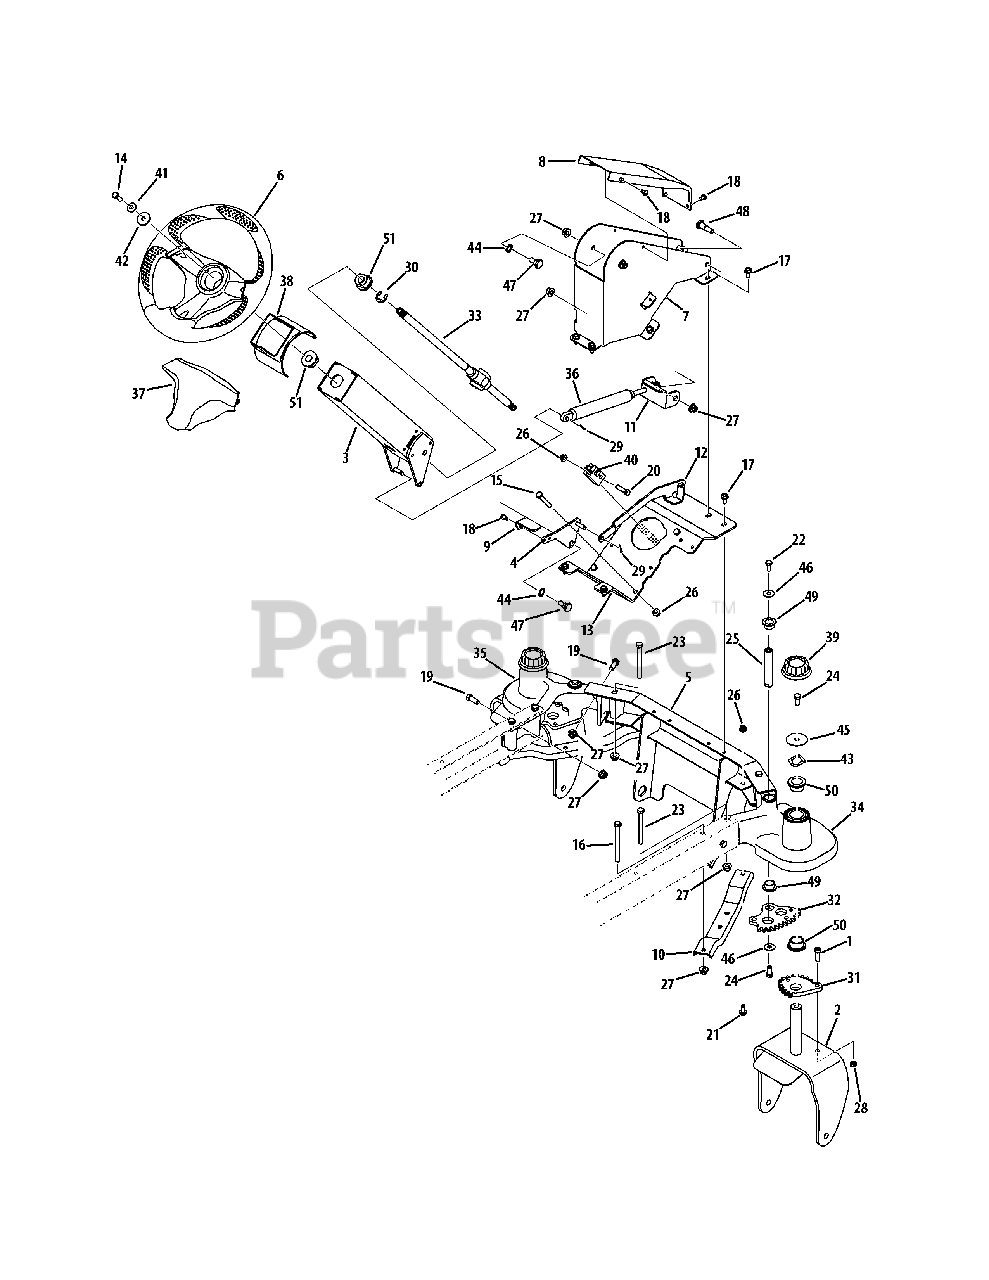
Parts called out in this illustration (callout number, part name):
1	Socket Head Screw, 5/16-18 x 1.00
2	Caster Bracket Assembly
3	Upper Steering Column Assembly
4	Tilt Release Pedal Assembly
5	Front Bumper Frame Assembly
6	Steering Wheel Assembly
7	Lower Steering Wheel Column
8	Lower Column Cover
9	Tilt Steering Pedal
10	Front Frame Brace
11	Damper Pivot Lower Bracket
12	Tilt Action Lever
13	Steering Mount Box Plate
14	Hex Screw, 5/16-18 x 1.00
15	Hex Screw, 5/16-18 x 2.25
16	Hex Screw, 3/8-16 x 4.00
17	Hex Washer Screw, 5/16-18 x .750
18	Screw, 1/4-20 x .5
19	Hex Screw, 3/8-16 x 1.00
20	Hex Screw, 5/16-18 x 1.25
21	Hex Washer Screw, 5/16-18 x 750
22	Hex Screw, 5/16-18 x .75
23	Hex Screw, 3/8-16 x 3.50
24	Hex Screw, 3/8-16 x .750
25	Pivot Gear Steering Shaft
26	Flange Lock Nut, 5/16-18
27	Flange Lock Nut, 3/8-16
28	Hex Lock Nut, 5/16-18
29	Cotter Pin, 3/32 x .750
30	E-Ring, .750
31	13-Tooth Variable Spur Gear
32	12-Tooth Variable Gear
33	Steering Shaft
34	RH Flange Bearing Caster Pivot
35	LH Flange Bearing Caster Pivot Axle
36	Locking Damper Cylinder, 80MM
37	Steering Wheel Cover
38	Column Cover
40	Steering Shaft Block
41	Bell Washer, .340 x .872 x .060
42	Flat Washer, .330 x 1.25 x .120
43	Wave Washer, 1.5 x 1.0 x .029
44	Wave Washer, .510 x.750 x .017
45	Flat Washer, .406 x 1.92 x .060
46	Flat Washer, .344 x 1.00 x .063
47	Shoulder Bolt, 3/8-16 x .496 x .336
48	Shoulder Screw, 3/8-16 x .50 x .66
49	Flange Bearing, 3/4 x .52
50	Flange Bearing, 1.0001 x 1.25
51	Flange Bearing, .630 x 1.50
